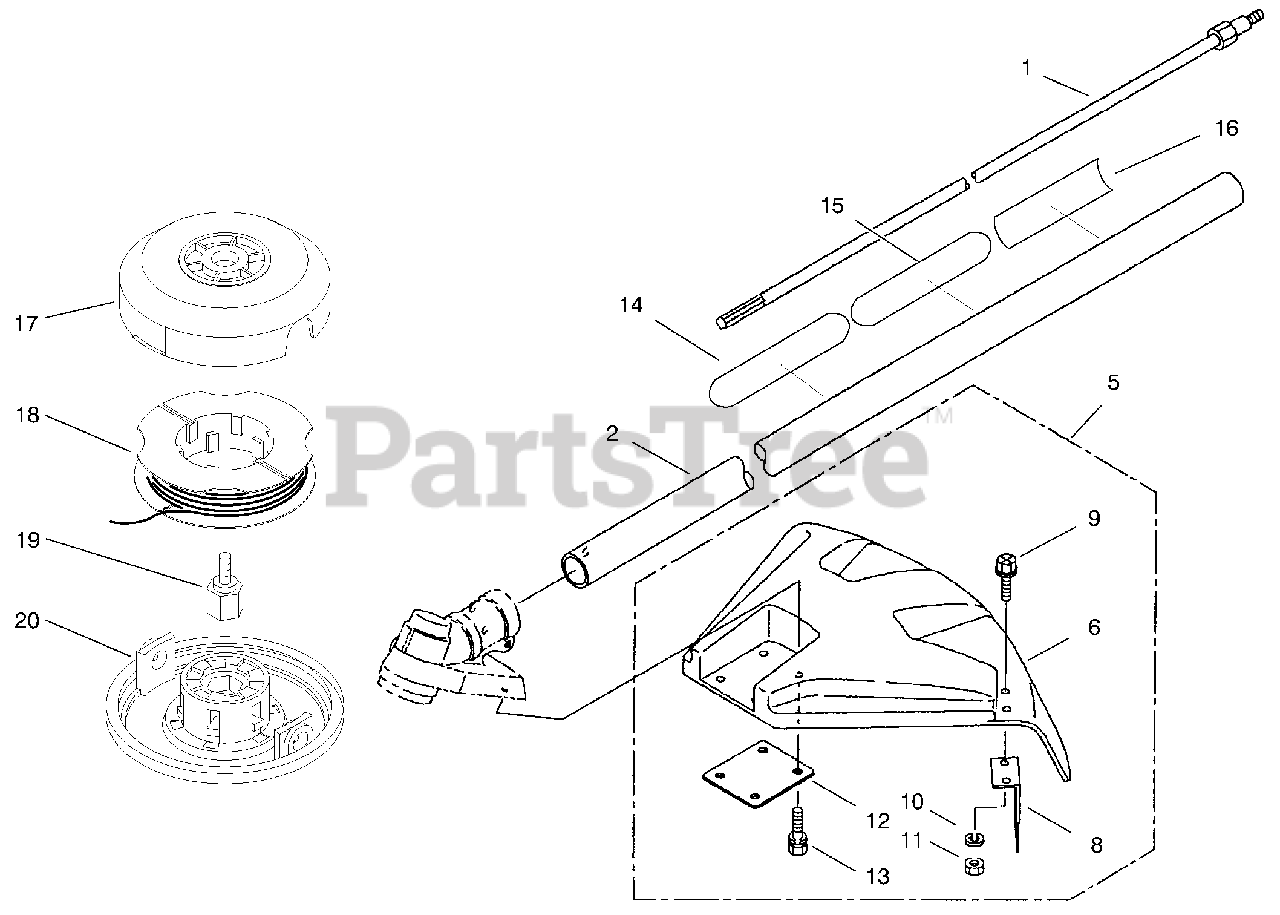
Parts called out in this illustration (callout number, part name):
1	Driveshaft Assembly
2	Driveshaft Tube Assembly (Incl. Ref. #14,15)
5	Safety Cover Assembly (Incl. Ref. # 6-13)
6	Safety Cover
8	String Cutter
10	Spring Washer
14	Decal-Caution
15	Decal-Caution
16	Decal-Toro
18	Spool with Line
19	Stud-Mounting
20	Base-Indexing
